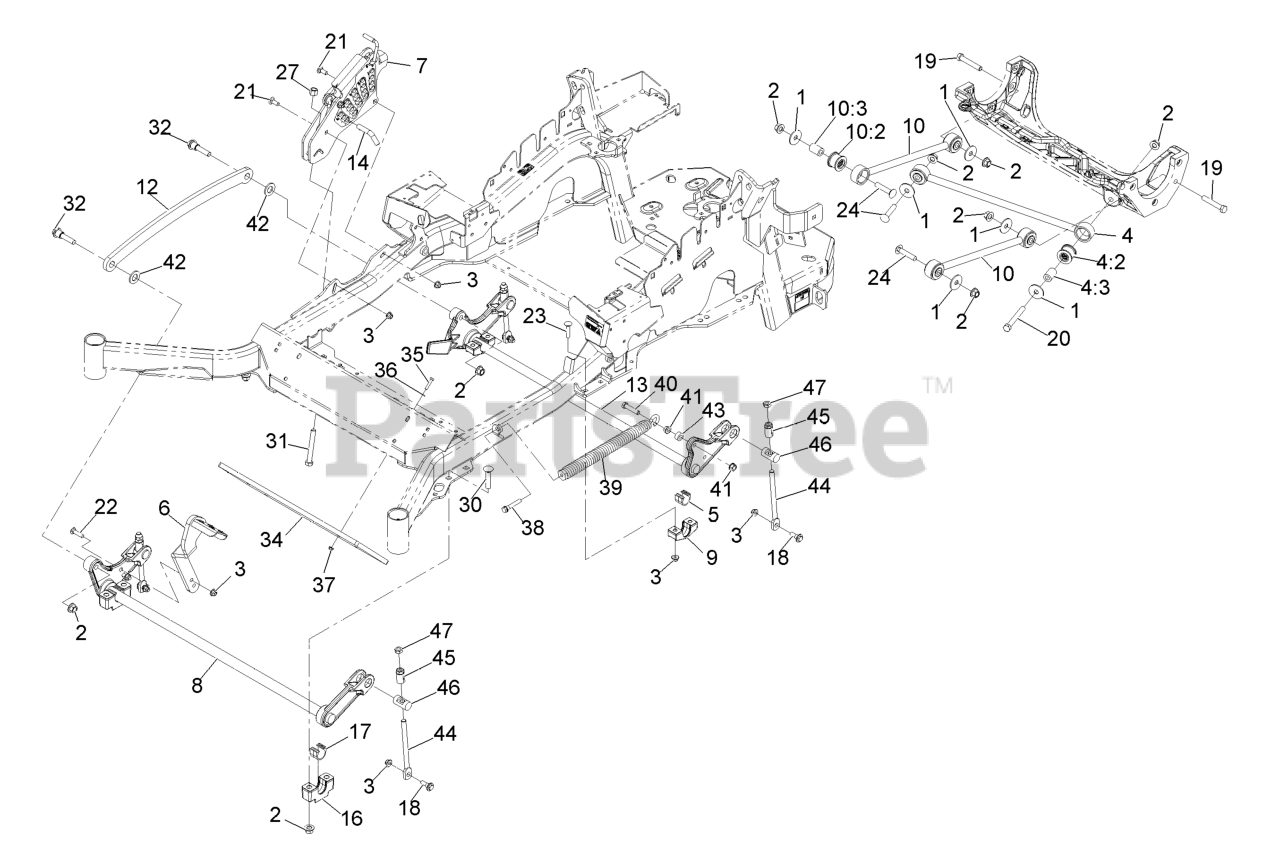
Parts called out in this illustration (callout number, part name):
1	WASHER-THRUST
2	Nut-Lock 1/2-13
3	NUT-HF, NI
4	PANHARD ROD ASM
4:2	BUSHING-SUSPENSION, RUBBER
5	BEARING-CROSS SHAFT, REAR
6	LEVER-FOOT
7	HOC ASM
10	DECK STRUT ASM
10:2	BUSHING-SUSPENSION, RUBBER
12	LINK-LIFT, DECK
13	LIFT-DECK, REAR
14	PIN-HOC
16	SUPPORT-CROSS SHAFT, BEARING
17	BEARING-CROSS SHAFT, FRON
18	SCREW-SHOULDER, HHF
19	SCREW-HH
20	SCREW-HH
21	BOLT-CARR
22	SCREW-CARR
23	SCREW-CARR
24	SCREW-CARR
27	NUT-LOCK, NI
30	Bolt-Carriage 1/2-13 X 2 1/2 Spl Neck
31	BOLT-TAP
32	SCREW-HHF, SHOULDER
34	WEIGHT,TOE BOARD
35	SCREW-HH
36	WASHER-FLAT
38	BOLT-SHOULDER
39	SPRING-EXTENSION
40	SCREW-HH
42	WASHER-FLAT
44	LINK-ADJUSTER, DECK LIFT
45	ADJUSTER-LIFT, DECK
46	TRUNNION
47	NUT-JAM
